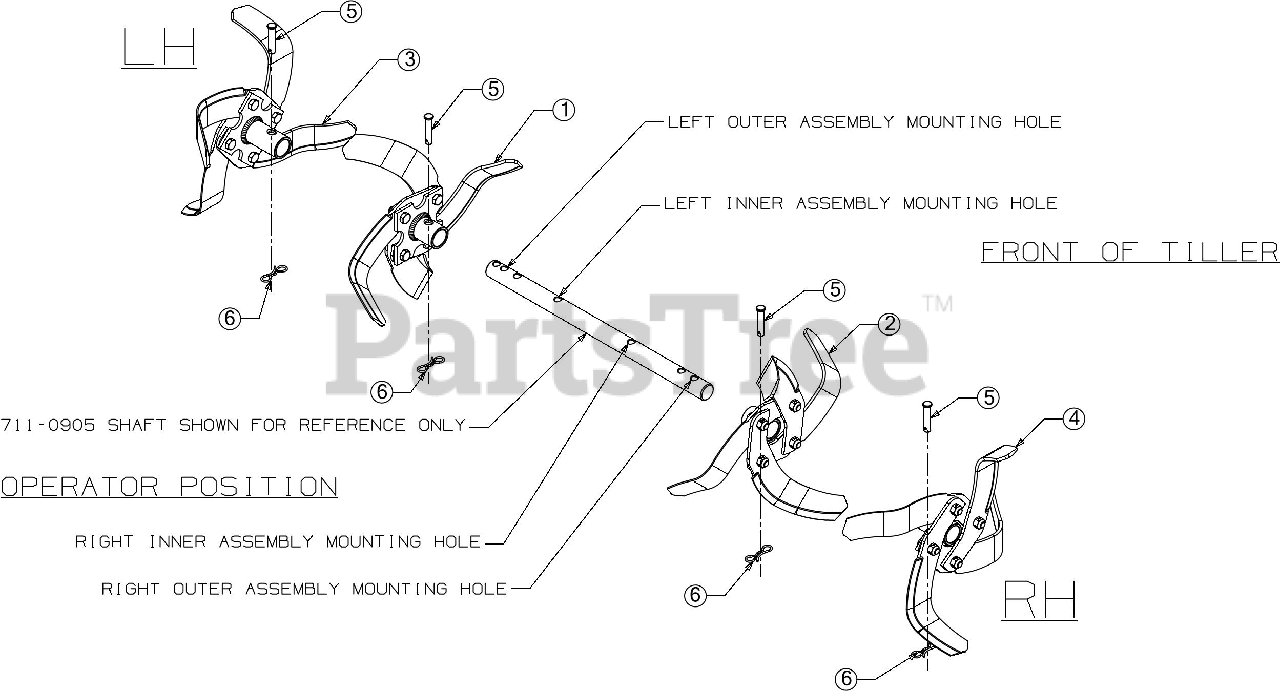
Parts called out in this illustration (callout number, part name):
1	BOLO TINE ASSEMBLY (INNER) (LH)
1	SCREW 3/8-16 X 1 GR5
1	LOCK NUT 3/8-16
2	BOLO TINE ASSEMBLY (INNER) (RH)
2	SCREW 3/8-16 X 1 GR5
2	LOCK NUT 3/8-16
3	BOLO TINE ASSEMBLY (OUTER) (LH)
3	SCREW 3/8-16 X 1 GR5
3	LOCK NUT 3/8-16
4	BOLO TINE ASSEMBLY (OUTER) (RH)
4	SCREW 3/8-16 X 1 GR5
4	LOCK NUT 3/8-16
5	CLEVIS PIN .375 X .1.75
6	PIN:COTTER
